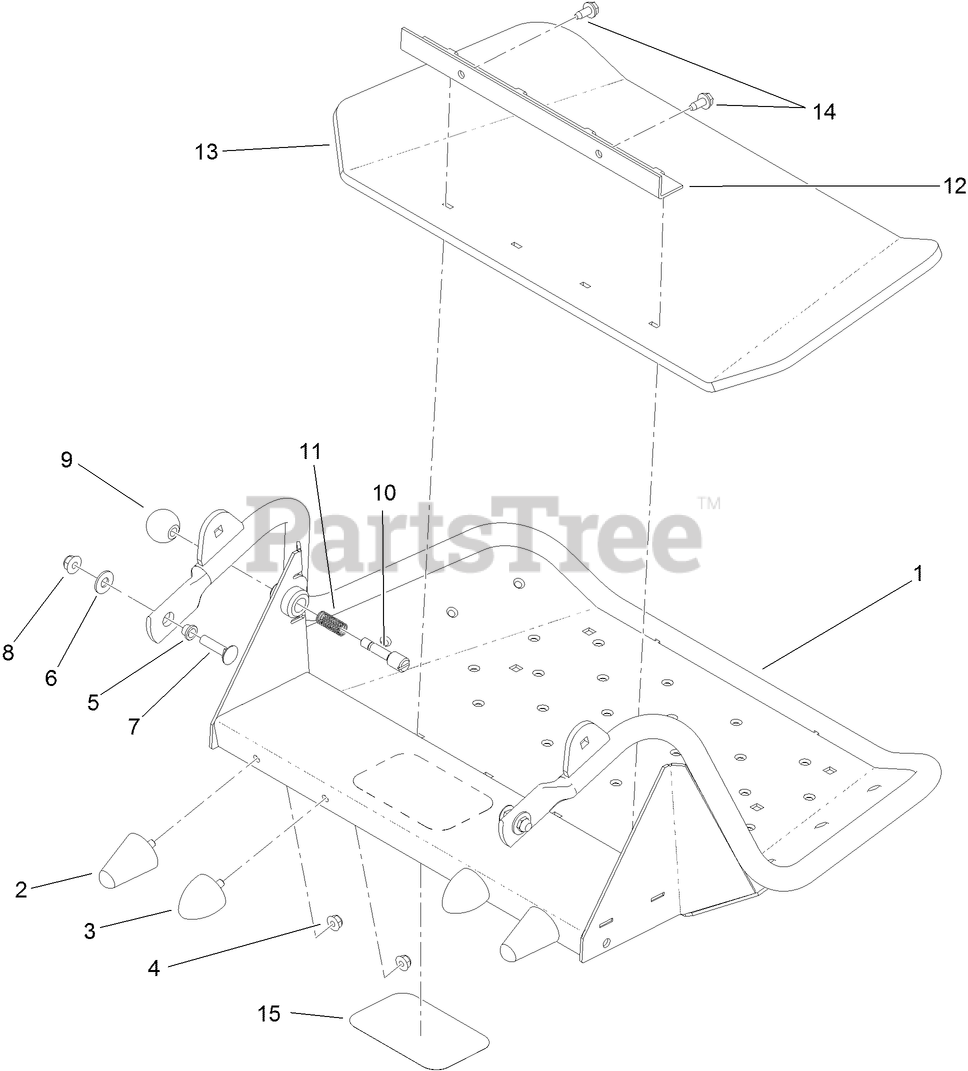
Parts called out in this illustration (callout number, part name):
1	PLATFORM
2	BUMPER-RUBBER
3	BUMPER-RUBBER
4	NUT-HF, NI
5	BUSHING-FLANGED
6	WASHER-FLAT
7	SCREW-CARR
8	NUT-HF, NI
9	KNOB-BALL
10	PIN-LATCH
11	SPRING
12	CLAMP-SHIELD
13	MAT-FOOT
14	SCREW-HWHTF
15	DECAL
